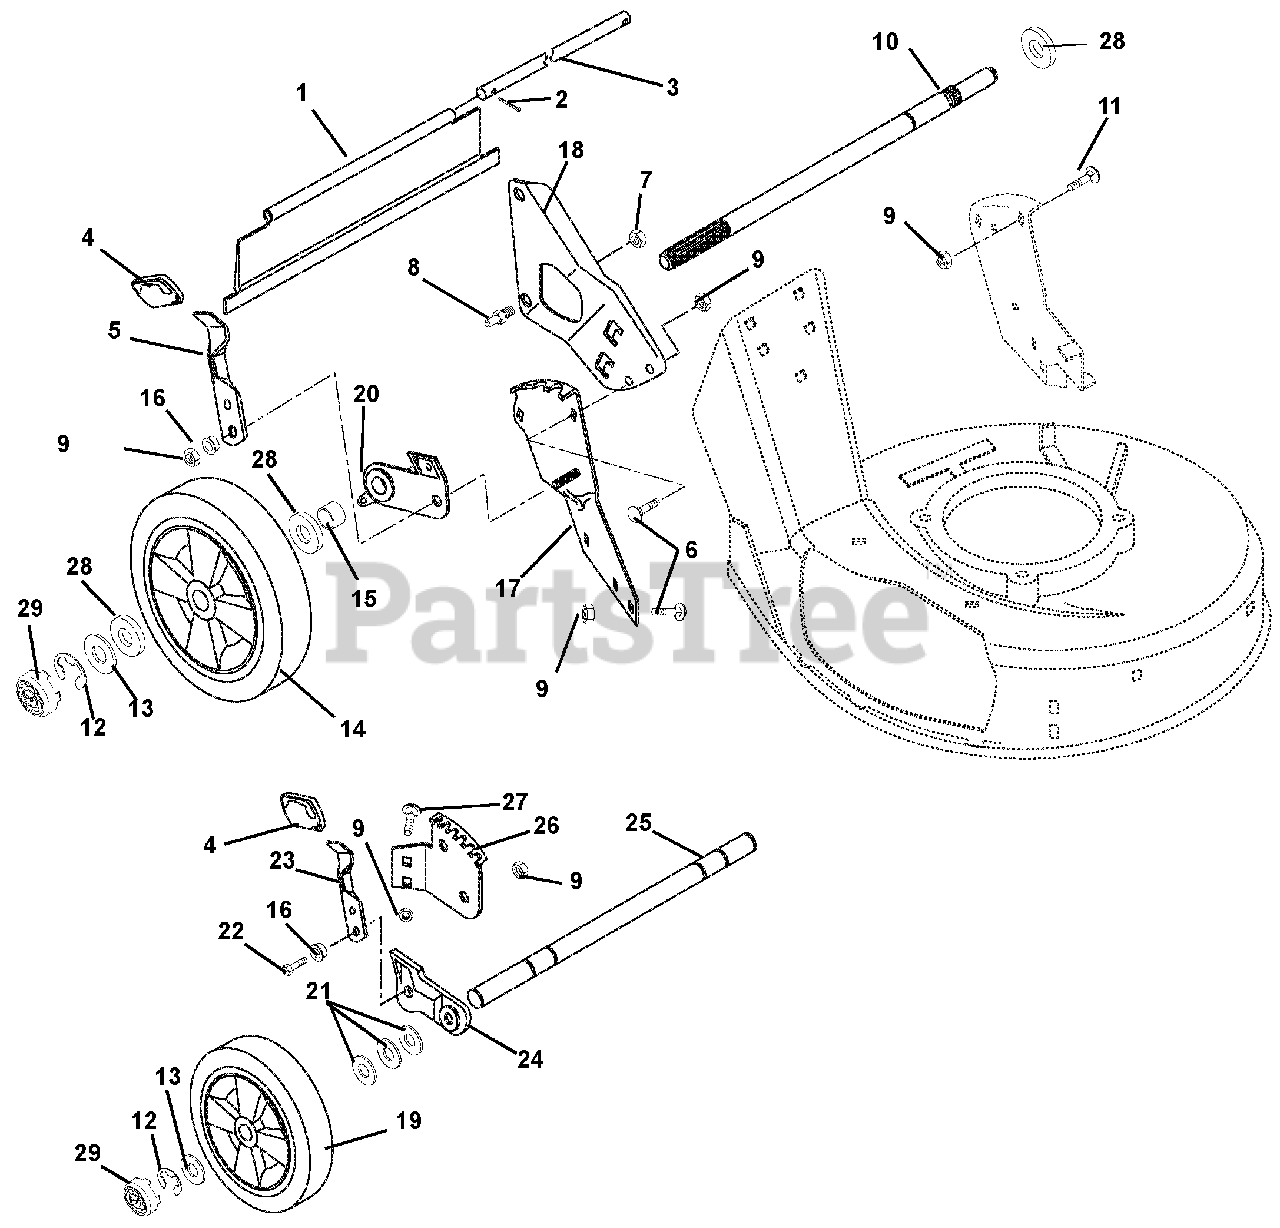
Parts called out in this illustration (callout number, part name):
1	REAR PROTECTIVE GUARD, S.P.
1	REAR PROTECTIVE GUARD, PUSH
2	@PIN-CTR .06X.50 EXTPRSQCT YWZ
4	KNOB
5	LEVER, HEIGHT ADJUSTMENT
6	@BLT-RHDSSQNK .31-18X.62 G5YZ
7	@NUT-LK-CTR .38-16 YWZC
8	HANDLEBAR STUD
9	@NUT-LK-TOP-FLG .31-18 YWZC
10	REAR AXLE,5/8 DIA
10	REAR AXLE-PUSH MOWER MM
11	@BLT-RHDSSQNK .31-18X1.00 G5YZ
12	RG-RTNG-EXT .500X.042 (E)
13	WSHR-FL-STL .505X.880X.072 YWZ
14	WHEEL, 10.3" OD X 2" WIDE LHS
14	WHEEL, 10.3" OD X 2" WIDE RHS
15	SPACER TUBE, SELF PROPEL
15	SPACER TUBE PUSH RH
16	BSHG-FLG .32X.500X.344X.880
17	QUADRANT, REAR LH
17	QUADRANT, REAR RH
18	RH HANDLEBAR MTG. BRKT
18	LH HANDLEBAR MTG. BRKT
19	WHEEL, 7.5" OD X 1.75" WIDE
20	REAR BRACKET & BEARING ASSY LH
20	REAR BRACKET & BEARING ASSY RH
20	REAR BRACKET & BEARING ASSEMBL
21	WSHR-FL-STL .52X.827X.062 YWZC
22	@BLT-HEX .31-18X1.00 GR5 YWZC
23	FRONT HEIGHT ADJUSTMENT LEVER
24	LEFT ADJUSTOR BRACKET ASSEMBLY
24	RIGHT ADJUSTOR BRACKET ASSEMBL
25	FRONT AXLE
26	FRONT QUADRANT, LH
26	FRONT QUADRANT, RH
27	@BLT-RDHDSQNK .31-18X.50 G5YZ
28	SPACER .531 X 1.00 X .225
29	HUB CAP, LM WHEEL
30	@NUT-LK-CTR .31-18 YWZC
